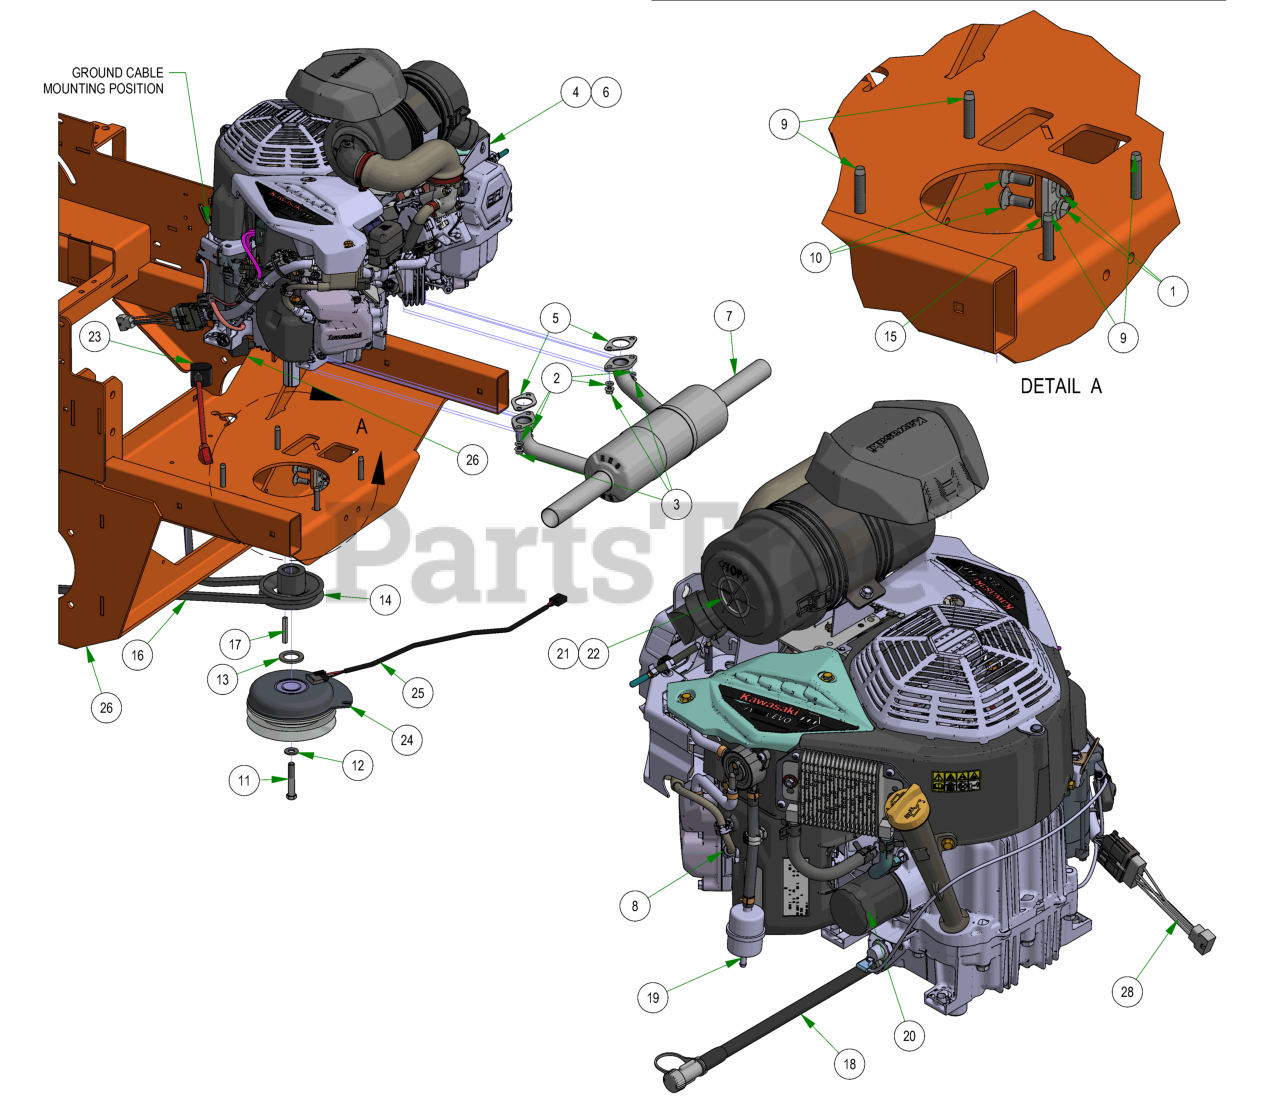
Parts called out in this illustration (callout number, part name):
1	3/8-16 NYLON INSERT FLANGE LOCKNUT (GR.F) ZINC
2	Exhaust Lock Washer
3	Exhaust Nut
4	Kawasaki FX720V EVO
5	Kawasaki EVO Exhaust Gasket
6	Kawasaki FX820V EVO
7	Rebel Kawasaki EVO Muffler
8	Spark Plug - Kawasaki
9	3/8-16 x 2 Hex/ Trilobe Horizontal Engine Bolt
10	3/8-16 X 1 CARRIAGE BOLT (GR.5) ZINC
11	7/16-20 X 2-1/2 HEX Bolt GR 8 W/ Patch
12	3/8 FLAT WASHER USS (1" OD) ZINC
13	1.140 ID X 1.750 OD X .132 THICK FLAT WASHER PLAIN
14	4 3/4 Motor Pulley
15	Rebel Clutch Tab
16	2019 Rebel Pump Belt
17	1/4 X 2 SQ MACHINERY KEY 1018 STL PLAIN
18	Kawasaki Oil Drain
19	Universal Inline Fuel Filter
20	Oil Filter
21	Canister Air Filter- Outer
22	Canister Air Filter- Inner
23	14" Red Battery Cable
24	Clutch Assembly
25	Clutch Pigtail
26	2023 Rebel Frame - Painted
27	Starter Cable
28	Harness Adaptor for Kawasaki EFI
